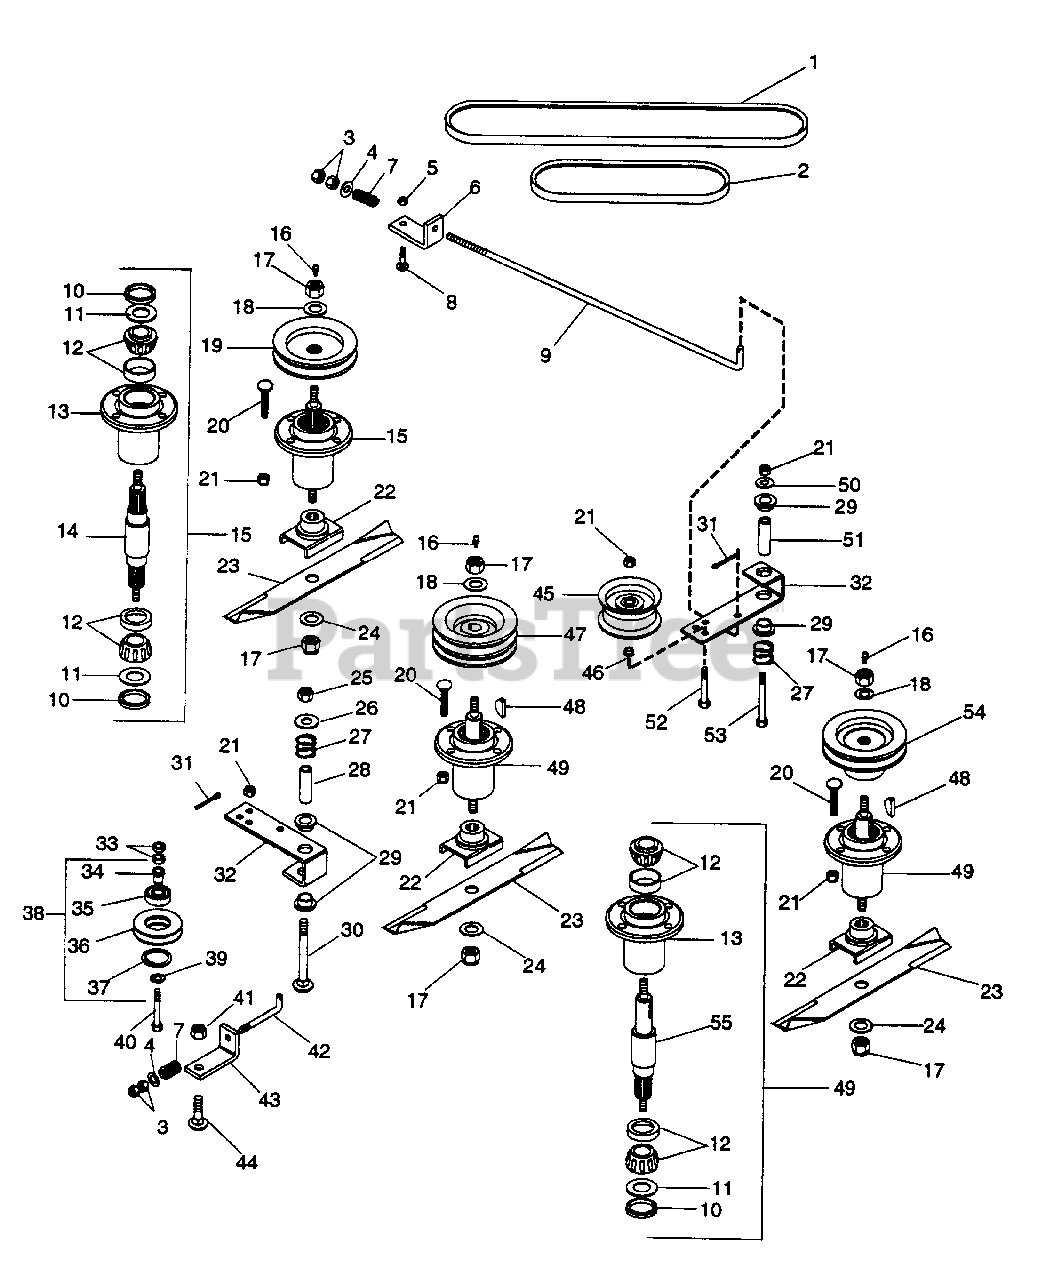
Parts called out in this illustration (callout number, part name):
1	BELT, PRO MWR
2	BELT, MOWER A44
3	NUT - HEX .375 - 16
4	WSHR - FL - STL .281 X .625 X .065
5	NUT - LK - NYL .312 - 18 PL
6	BRKT, BELT TENSIONER
7	SG - COMP .188 X 1.66 X 2.0
8	BLT, CARRIAGE 5/16 - 18 X 1.0
9	ROD, IDLER L.H.
10	SL, STEEL
11	WSHR - FL - STL .97 X 1.865 X .03
12	ASM, BEARING CUP & CONE
13	HSG, BEARING
14	SHFT, SPINDLE
15	SPNDL, ASSEMBLY
16	FTG, LUBE 1/8
17	NUT, LK 5/8 - 1.1 HEX W/INSR
18	WSHR - FL - STL .687 X 1.312 X .135
19	SHEAVE, SPINDLE
20	BLT - RDHDSQNK .38 - 16 X 1.375
21	NUT - LK - NYL .375 - 16 PL
22	WLDMT, BLADE CRADLE
23	BLD, 50 INCH MOWER
24	WSHR - FL - STL .656 X 1.312 X .095 PL
25	NUT - LK .50 - 13 HEX TYPE N
26	WSHR - FL - STL .531 X 1.250 X .100
27	SG - COMP
28	BUSH., S .560 X .750 X 2.44 ST
29	BSHG - FLG .762 X 1.0 X .580 X 1.48 NY
30	BLT - RDHDSQNK .50 - 13 X 3.50
31	PIN - COTR .09 X .75 PL
32	ARM, IDLER PIVOT
33	BUSHING .406 X .750 X .188
34	BSHG - FLG .786 X 1.0 X .79
35	BRG - BALL 1.85 X .787 X .55
36	SHEAVE, IDLER
37	RG - RTNG - INT 2.054 X .062
38	ASM, IDLER SHEAVE
39	WASHER, FLT .375 X 1.125 X .065
40	BLT - HEX .38 - 16 X 2.00 PL GR 5
41	NUT - LK - NYL .50 - 13 PL
42	ROD, IDLER
43	BRKT, BELT TENSIONER
44	BLT - RDHDSQNK .50 - 13 X 1.50
45	IDLER - FLAT 4 - .687 X .38
46	BSHG - FLG .406 X .88 X .270 X .140
47	SHEAVE, SPINDLE
48	KEY, WDRF 1/4 X 1 HRD #15
49	ASM, SPINDLE
50	WSHR - FL - STL .438 X 1.000 X .083
51	BUSH., S .437 X .750 X 2.44 ST
52	BLT - HEX .38 - 16 X 2.25 GR 5
53	BLT - HEX .38 - 16 X 3.25 PL GR 5
54	SHEAVE, SPINDLE
55	SHFT, SPINDLE
